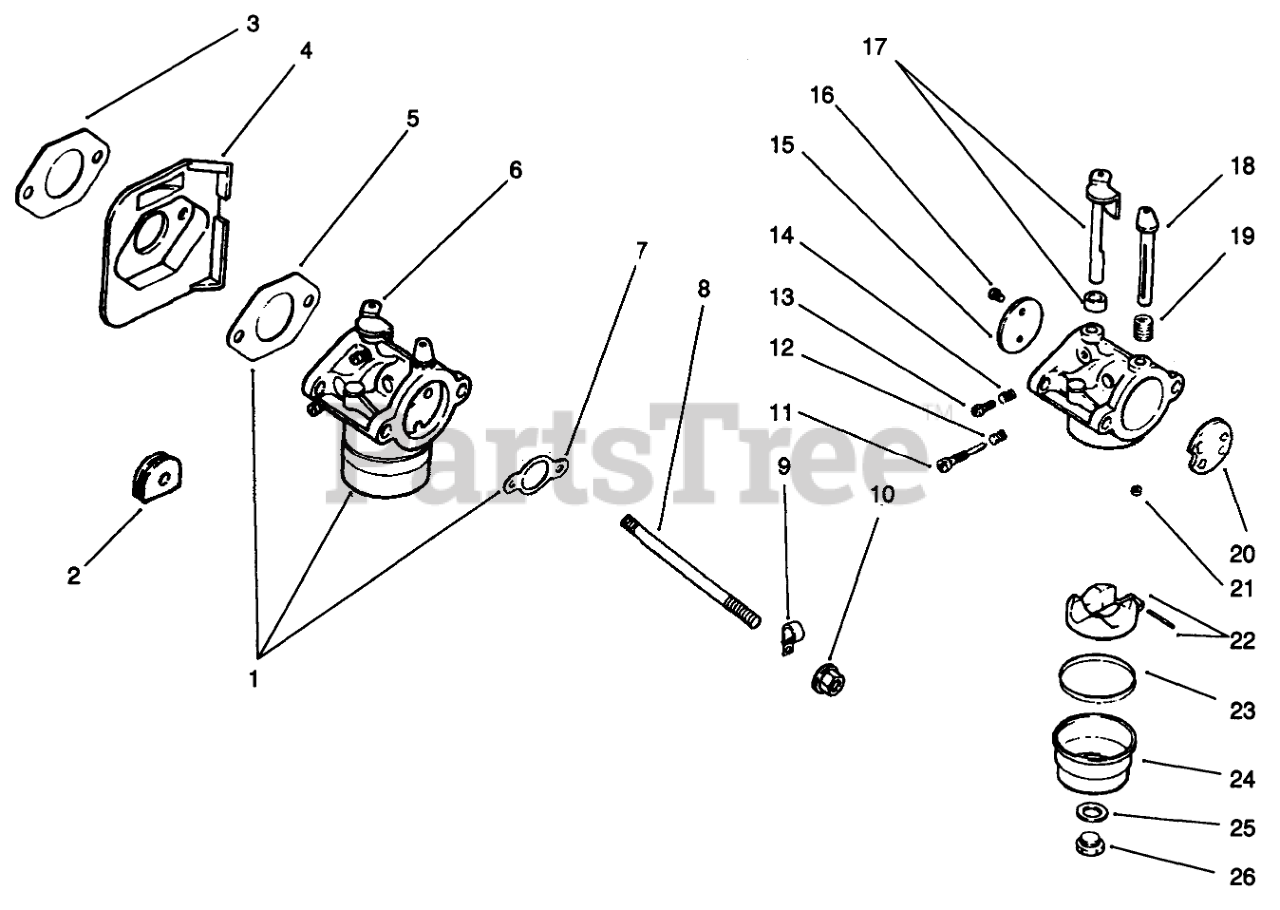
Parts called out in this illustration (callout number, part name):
1	Kit-Carburetor
2	Grommet
3	Gasket
4	Deflector
5	Carburetor Assembly(Ref.)
6	Gasket
7	Gasket
11	Needle-Idle
12	Spring-Idle
13	Screw-Idle
14	Spring-Idle
15	Plate-Throttle
16	Screw-Throttle Plate
17	Shaft-Throttle
18	Shaft-Choke
19	Spring
20	Plate-Choke
21	Jet-Main
22	Kit-Float
23	Gasket-Bowl
24	Bowl
25	Gasket
26	Screw-Bowl
